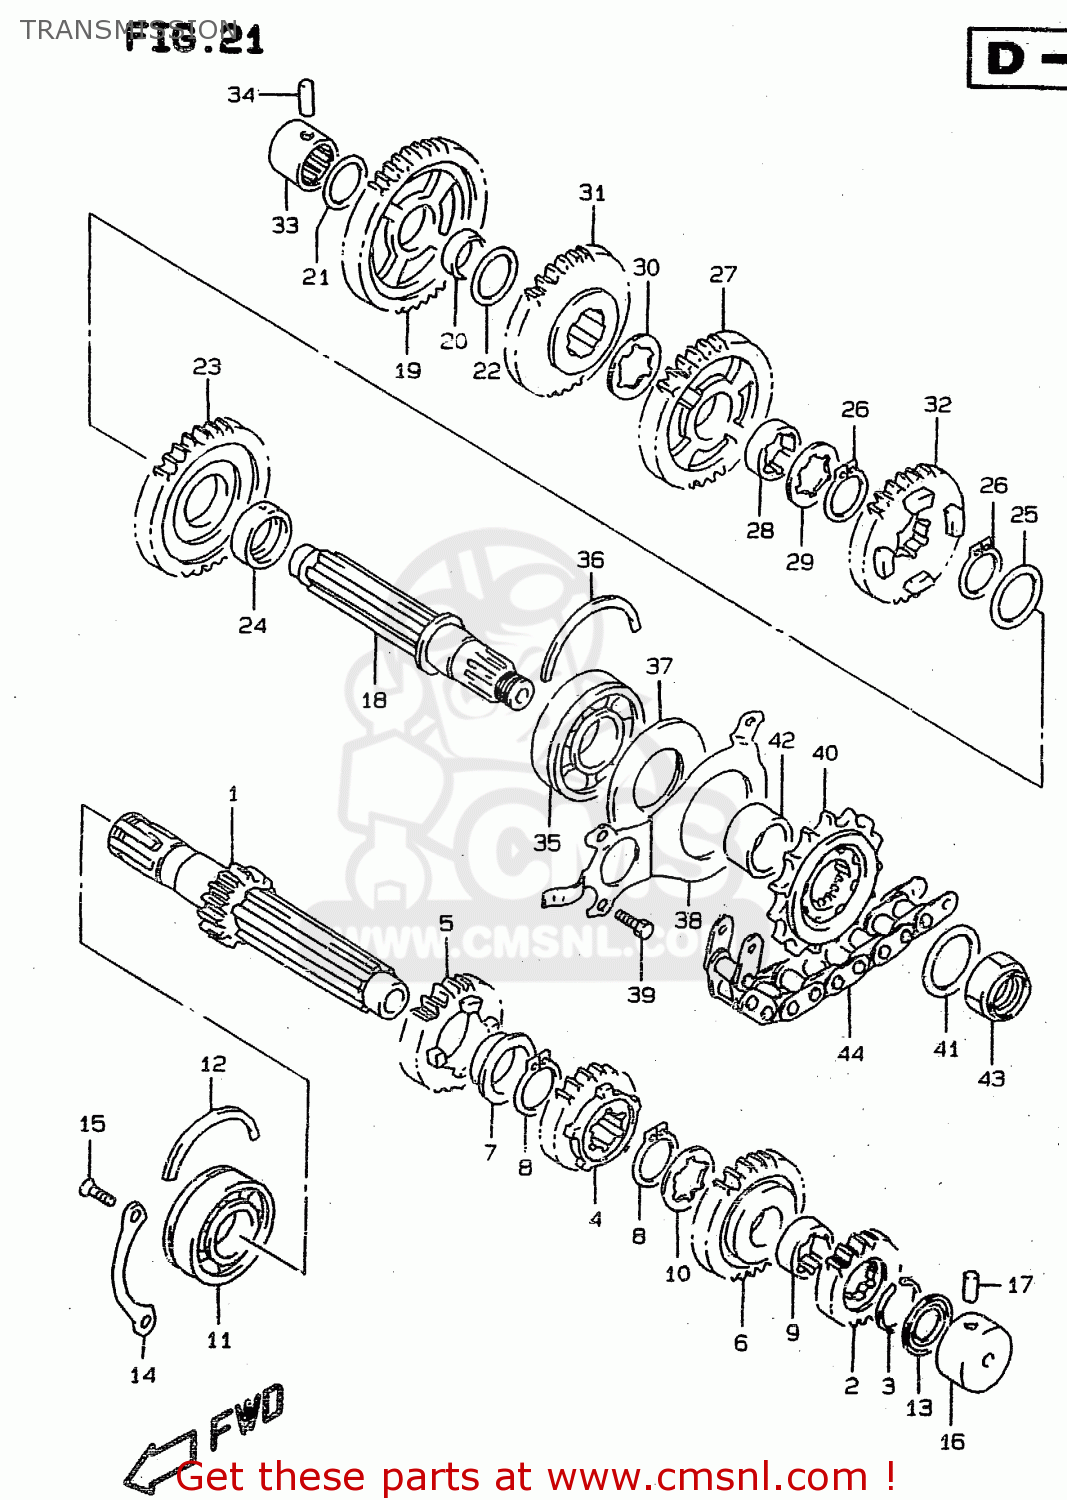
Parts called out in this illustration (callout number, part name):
1	SHAFT,COUNTER
2	GEAR,2ND DRIVE
3	CIRCLIP
4	GEAR,THIRD DRIVE
5	GEAR,FOURTH DRIVE
6	GEAR,5TH DRIVE
7	BUSH(28X32X2)
8	CIRCLIP
9	BUSH
10	WASHER,LOCK
11	BEARING(25X62X17)
12	C-RING
13	SEAL,OIL(20X31.2X2.7)
14	RETAINER,CNTR SHAFT BEARING
15	SCREW ,6X16
16	BEARING
17	PIN
18	SHAFT,DRIVE
19	GEAR,1ST DRIVEN
20	BUSHING
21	WASHER
22	WASHER
23	GEAR,2ND DRIVEN
24	BUSH(28X32X11)
25	SHIM(28X38X1)
26	CIRCLIP
27	GEAR,3RD DRIVEN
28	BUSH,3RD DRIVEN GEAR
29	WASHER,LOCK
30	WASHER,LOCK
31	GEAR,4TH DRIVEN
32	GEAR,5TH DRIVEN
33	BEARING(20X34X20)
34	PIN
35	BEARING(28X70X18)
36	C RING
37	SEAL,OIL(34.8X70X6)
38	RETAINER,DRIVE SHAFT OIL SEAL
39	BOLT
40	SPROCKET,ENGINE(15T)
41	WASHER,THRUST
42	SPACER(25X36X17.7)
43	NUT
44	CHAIN ASSEMBLY,DRIVE 110LE
